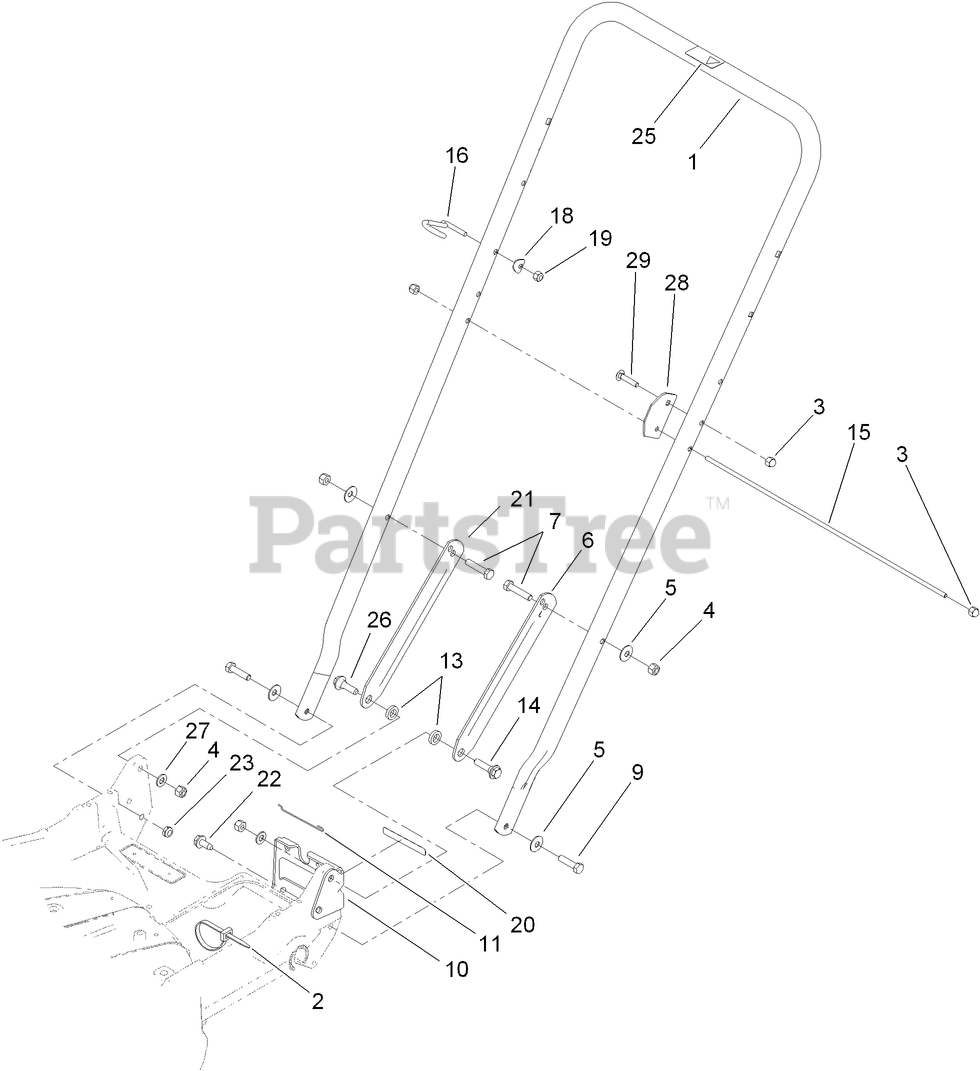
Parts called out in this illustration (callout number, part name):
2	TIE-CABLE
3	NUT-CAP
4	NUT-LOCK, NI
5	WASHER-BELLEVILLE
6	LATCH-HANDLE, LH
7	SCREW-HH
9	SCREW-HH
10	BRACKET-ADJUSTMENT, TRACTION
11	RETAINER-CABLE
13	SPACER
14	SCREW-SHOULDER
15	ROD-SUPPORT, BAG
16	GUIDE-ROPE
18	WASHER
19	NUT-LOCK, NI
20	DECAL-POSITION, GEAR
21	LATCH-HANDLE, RH
22	SCREW-HWHTF
23	NUT-LOCK, NI
25	DECAL-PROTECTION, EAR
26	SCREW-SHOULDER
27	WASHER-PLAIN
28	PLATE-ALIGNING, BAG
29	SCREW-CARR
